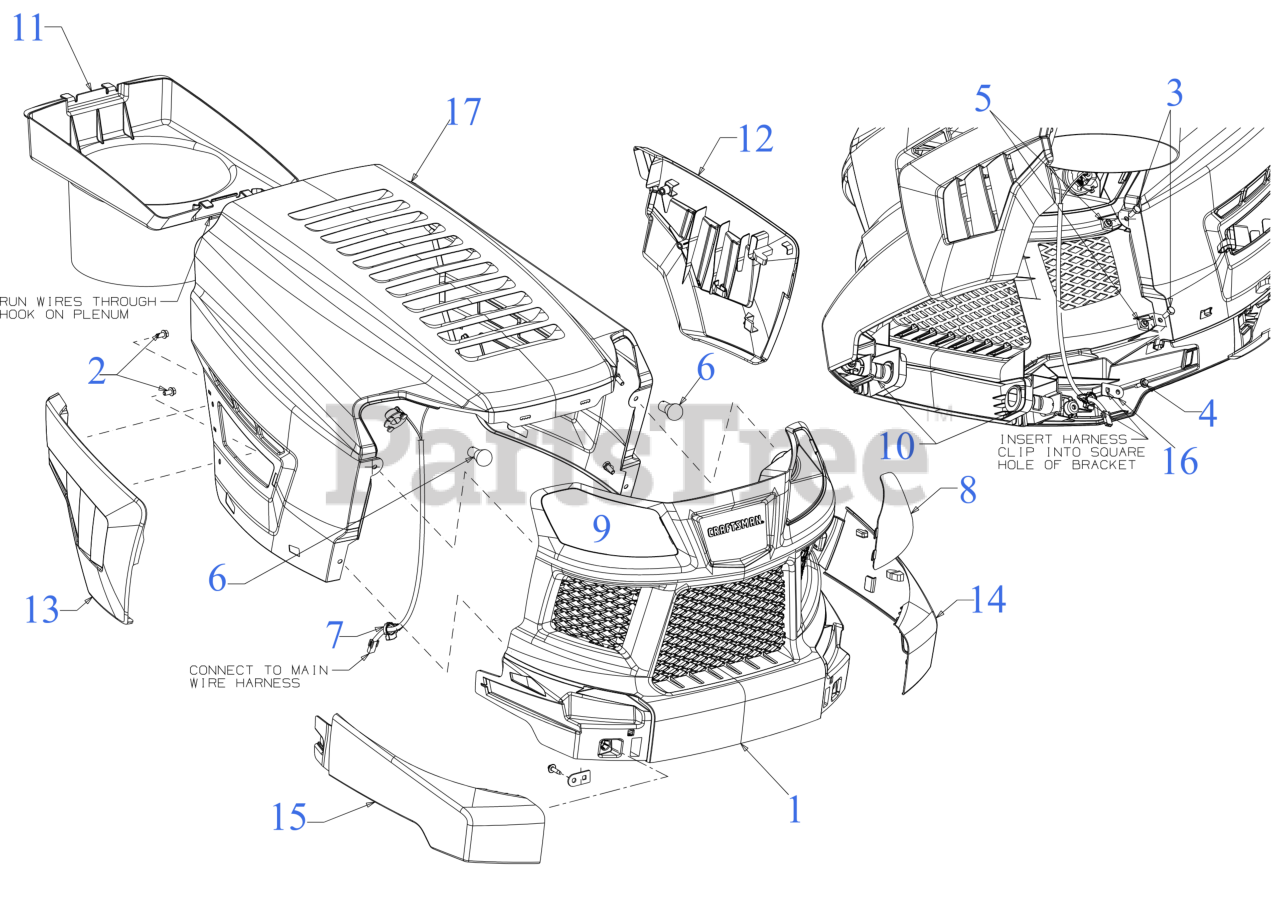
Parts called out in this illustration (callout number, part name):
1	GRILLE
2	HEX SCREW 1/4-15 x .50
3	SCREW 1/4-20 x .62 SPEC GR5
4	SCREW 1/4-10 x .750
5	SQUARE NUT 1/4-20
6	MINIATURE LAMP-12V #1156
7	HEADLIGHT HARNESS
8	GRILLE LENS (LH)
9	GRILLE LENS (RH)
10	HOOD PIVOT PIN
11	HOOD PLENUM
12	HOOD SIDE COVER (LH)
13	HOOD SIDE COVER (RH)
14	GRILLE PANEL (LH) (LIBERTY RED)
15	GRILLE PANEL (RH) (LIBERTY RED)
16	HARNESS CLIP BRACKET
17	HOOD (NO SCOOP)
